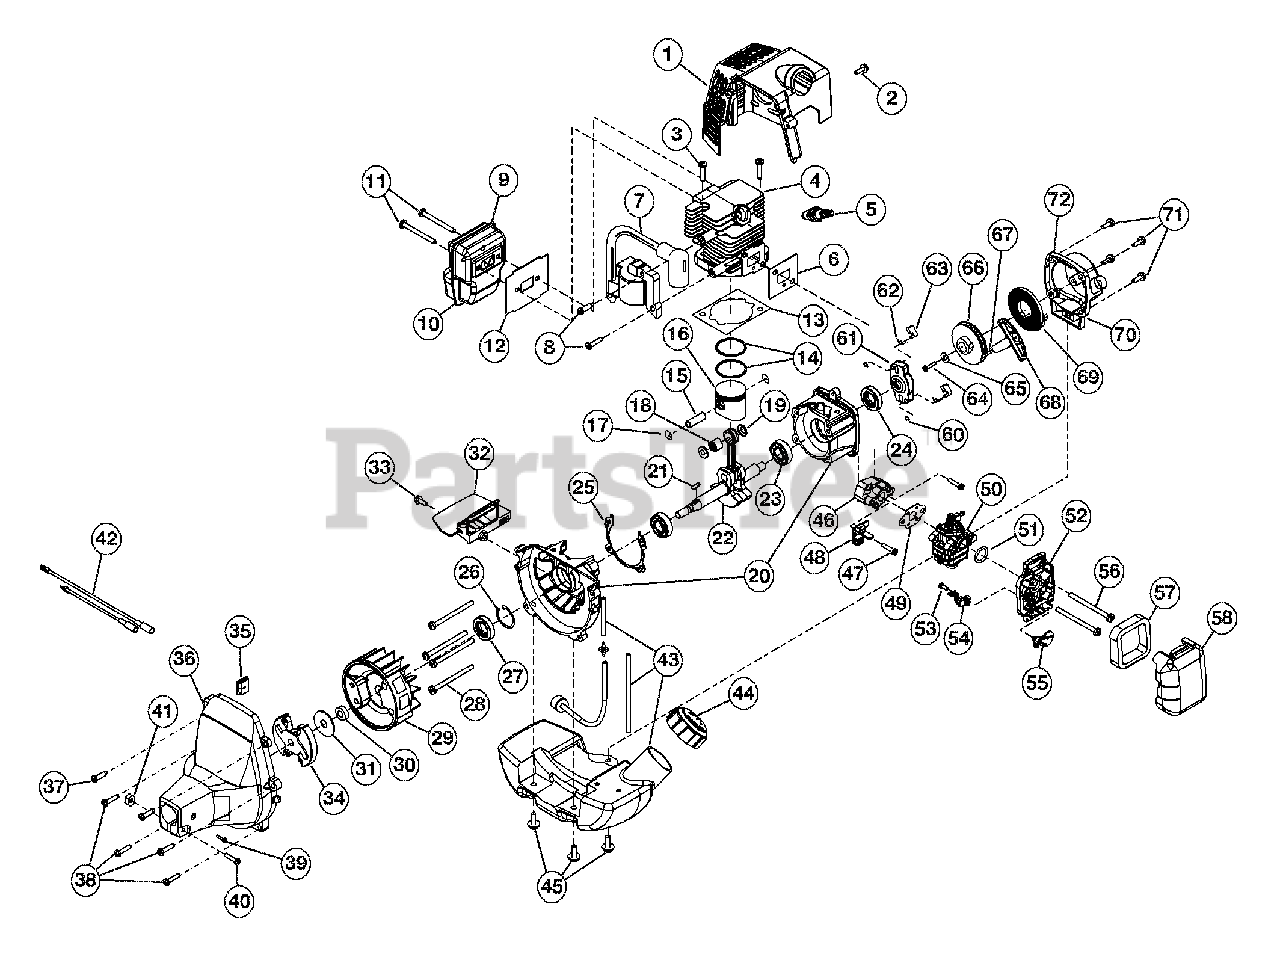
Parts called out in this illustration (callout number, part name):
1	Engine Cover
2	Cover Screw
3	Cylinder Bolt
6	Insulator Gasket
7	Module Assembly
8	Module Screw
9	Muffler Assembly
11	Muffler Mounting Bolt
12	Muffler Gasket
13	Cylinder Gasket
18	Needle Baring
19	Piston Spacer
20	Crankcase Assembly
22	Crankshaft Assembly
24	Rear Oil Seal
25	Crankcase Gasket
27	Front Oil Seal
28	Crankcase Screw
31	Clutch Washer
32	Muffler Plate
33	Muffler Plate Screw
35	Wire Grommet
36	Clutch Housing
37	Upper Housing Screw
38	Lower Housing Screw
39	Anti-Rotation Screw
40	Clamp Screw
42	Lead Wire Assembly
43	Fuel Tank Assembly
45	Fuel Tank Screw
47	Insulator Screw
48	Throttle Bracket
49	Carburetor Gasket
50	Carburetor
52	Air Cleaner Assembly
53	Choke Screw
54	Choke Lever
55	Choke Plate
56	Air Cleaner Screw
58	Air Cleaner Cover
59	Pawls Assembly
64	Recoil Pulley Retaining Screw
65	Recoil Pulley Retaining Washer
66	Recoil Pulley
68	Starter Handle
69	Recoil Spring
70	Recoil Pulley Cover
71	Recoil Pulley Screw
72	Recoil Assembly
